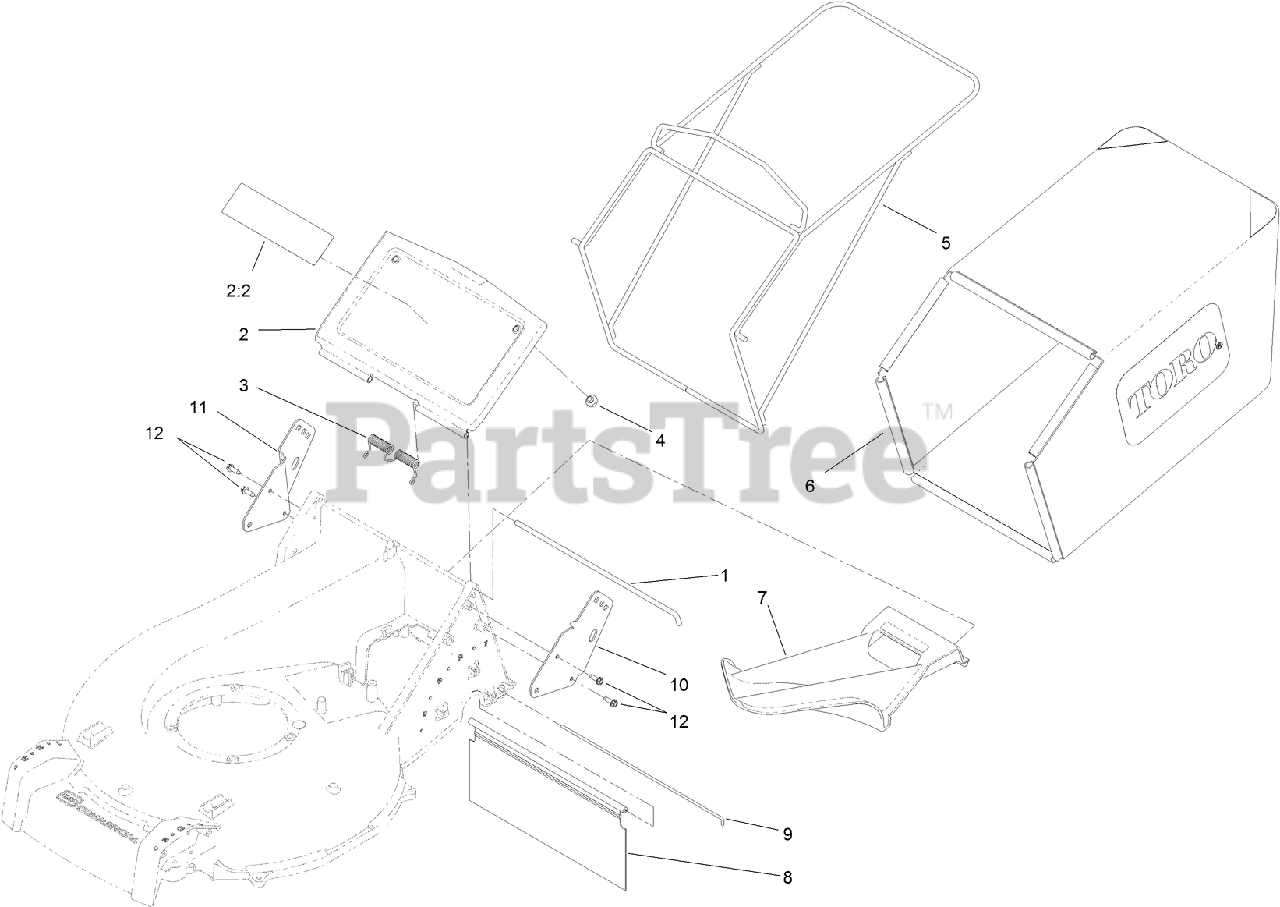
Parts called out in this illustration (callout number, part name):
1	ROD-DOOR, BAG
2	BAG DOOR ASM
2:2	DECAL-WARNING
3	SPRING-TORSION
4	BUMPER
5	FRAME-BAG
6	BAG-GRASS
7	PLUG-MULCH
8	SHIELD-TRAILING
9	ROD-SHIELD, TRAILING
10	BRACKET-MOUNT, HANDLE (LH)
11	BRACKET-MOUNT, HANDLE (RH)
12	SCREW-HWHTF
